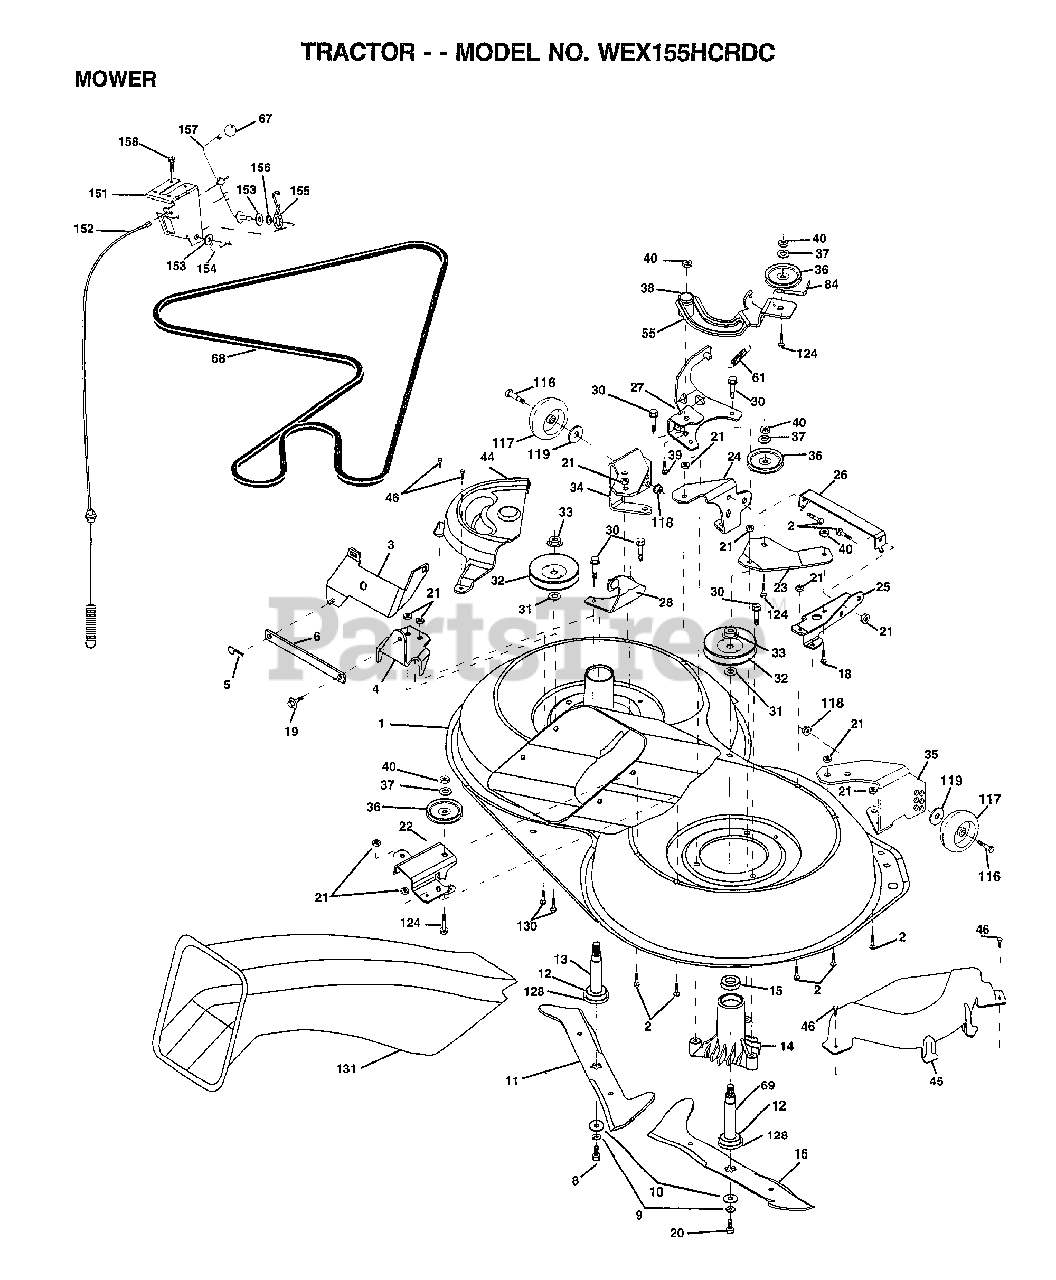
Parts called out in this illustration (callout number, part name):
1	HOUSING ASM MOWER
2	BOLT
3	BRKT.ASM.S-BAR.CHASSIS
4	BRKT BAR SWAY DECK
6	BAR.SWAY.92.CRD
8	BLADE BOLT
10	WASHER.HARD.BLADE
12	BEARING.BALL
14	HSG ASM MANDREL
15	BEARING
16	BLADE
18	BOLT D
19	BOLT SHD 5/16-18
20	BOLT.3/8-24X1.25
22	BRKT IDLER SPRT
23	BRKT IDLER SPRT
24	BRKT SUSPENSION
25	BRKT SUSPENSION
26	BRACE.SUPT.SUSP.FRT.CRD
27	BRKT ASM SUSP
28	BRKT ASM SUSP
30	"SCREW-THD ROLL,WA"
31	WASHER
32	PULLEY.MANDREL.42
34	BRKT GAUGE WHEEL
35	BRKT GAUGE WHEEL
36	PULLEY.IDLER.4.25
37	WASHER
38	SPACER HUB ARM IDLER
39	BOLT
44	COVER MANDREL
45	COVER MANDREL
46	SCREW.1/4-20X5/8
55	ARM IDLER
61	SPRING.TENSION.BELT
67	KNOB T(3/8 HOLE)
68	HEX-BELT
69	SHAFT.ASM.W/LWR.BRG.RH.THD
84	"KEEPER-BELT,IDLER"
116	BOLT.SHOULDER
117	WHEEL GAGE DONUT
118	LOCKNUT
119	WASHER
124	BOLT.3/8-16X1.50
128	WASHER.FELT.
131	CHUTE.BAGGER.CRD
151	BRKT CLUTCH CABLE
152	CABLE CLUTCH CRD SERVICE
153	WASHER FLAT
154	SPRING RETAINER
155	SPRING RETENTION LVR CLUTCH CAB
156	SPACER
157	ROD.CLUTCH.CABLE.3/8
158	SCREW LT
